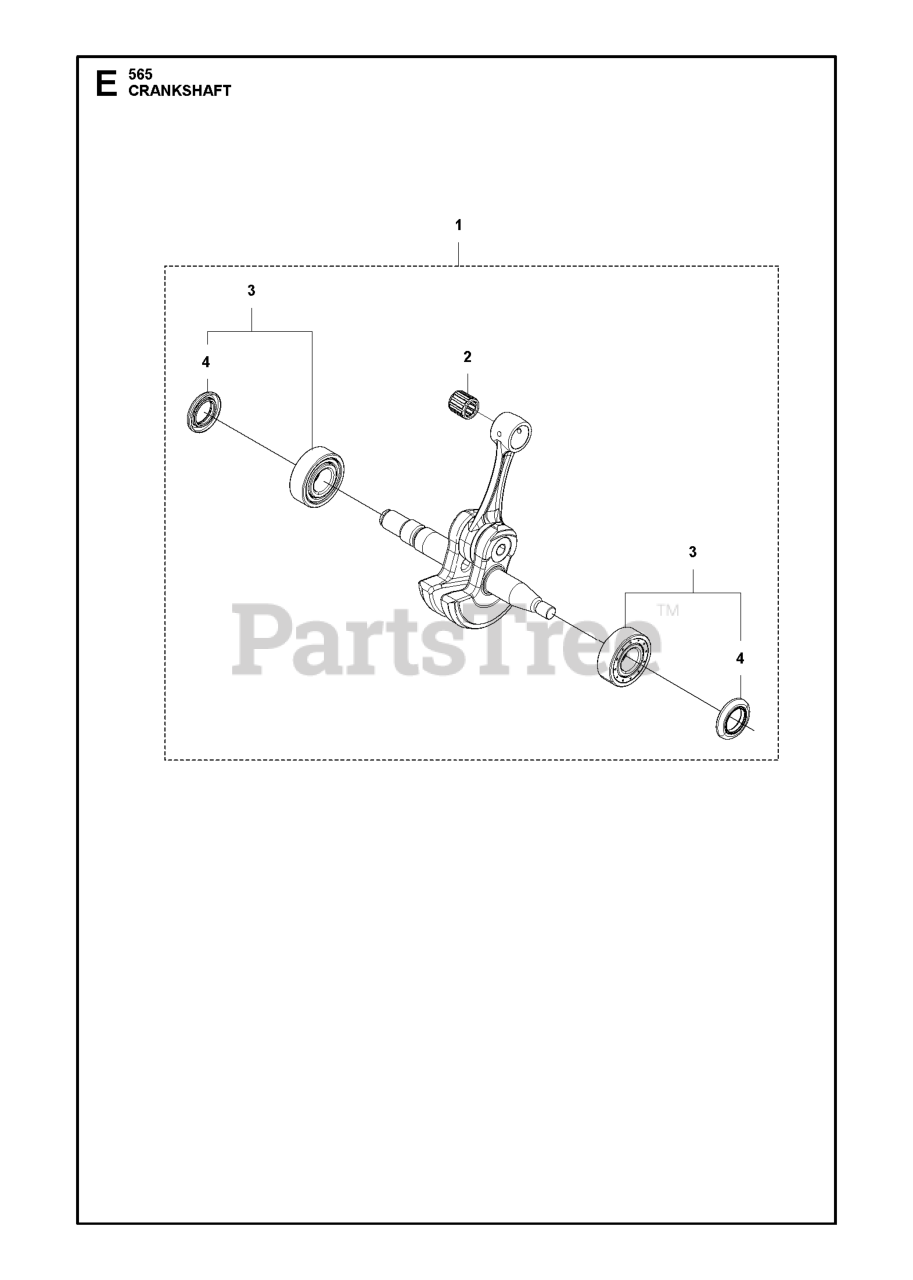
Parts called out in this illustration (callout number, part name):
1	CRANKSHAFT ASSY H565 SPARE PAR
2	NEEDLE BEARING PISTON PIN 12X1
3	BALL BEARING 6203/W12.5/D39-C4
4	RADIAL SEAL 24.5X32.7X3
